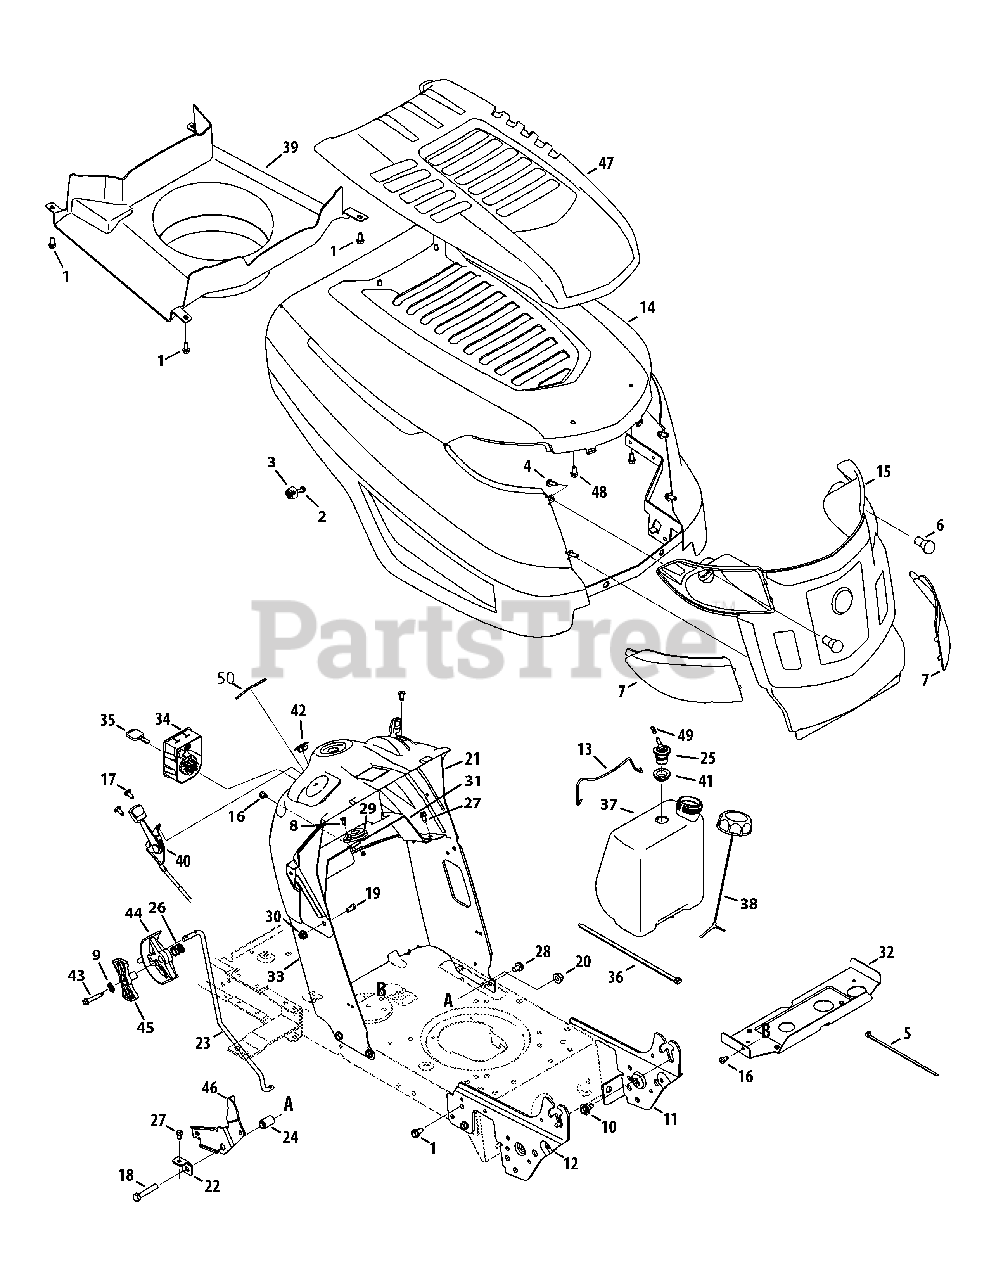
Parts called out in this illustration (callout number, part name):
1	Screw 5/16-18 x .750
2	Screw, #12-16 x 1.25
3	K-Style Bumper
4	Screw, 1/4 x .750
5	Cable Tie
6	Miniature lamp 12V socket
7	Grill Lens - LH
7	Grill Lens - RH
8	Screw, #10-16 x .500
9	Lock Washer, 1/4
10	Shoulder Screw .43 x .29
11	Suppport Bracket LH
12	Suppport Bracket RH
14	Hood, w/ scoop
16	Screw, 1/4-20 x .500
17	Screw 1/4-20 x .500
18	Hex Screw 3/8-16 x 2.00
19	Hex Screw, 5/16-18 x .625
20	Flange Lock Nut 3/8-16
21	Dash, Upper
22	Speed Latch Tab
23	Speed Control Rod
24	Flange Spacer .39 x .671 x 1.095
25	Rollover Valve
26	Compr. Spring, .72 OD x .78
27	Tap Screw, 1/4-20, 0.625
28	Screw 5/16-18 x .625
29	Bearing, .628 ID x 1.36
30	Flange lock Nut 5/16-18
31	Bracket, Steering Support
32	Gas Tank Support Bracket
33	Dash, Lower NWNDW
34	Key Switch Module
35	Key, Assembly
36	Cable Tie
37	1.36 Gallon Fuel Tank
38	Fuel Cap, 2.25"
40	Throttle/Choke Cable, 28"
41	Rubber Grommet, 23 x 3.55
42	Choke Plug
43	Hex Washer Screw, 1/4-20 x 1.50
44	Shift Lever
45	Index Control
46	Transmission Speed Latch, RMC
48	Screw, 1/4-15 x 0.50
49	Hose Vent, 3/16 EPA
50	Ammeter Plug
